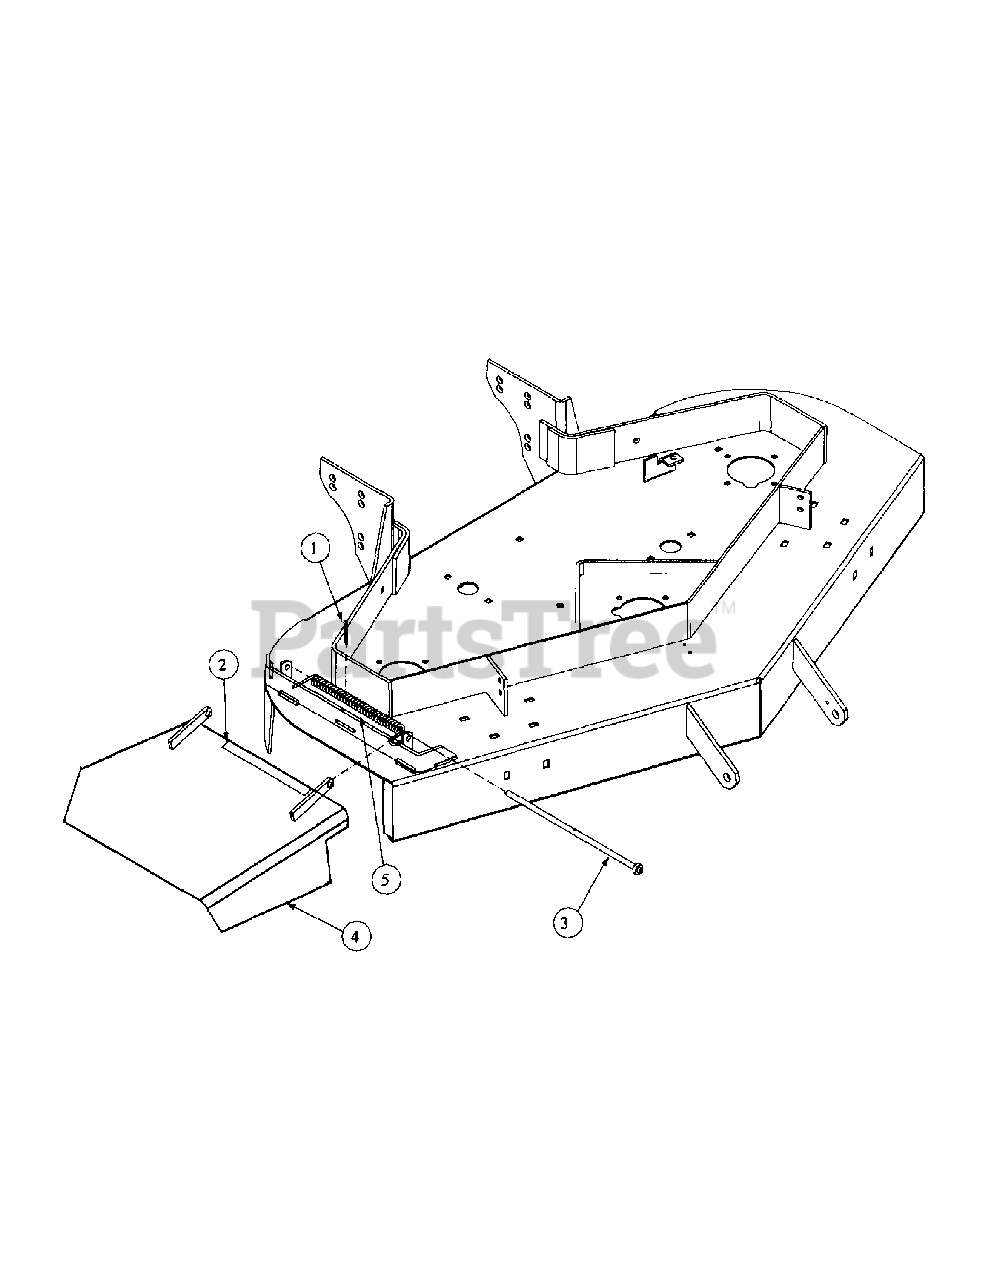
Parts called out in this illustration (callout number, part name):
1	Cotter Pin, 5/32 x 1-1/2, Zinc
2	Decal, Cut Line
3	Pin Deflector, Weldment
4	Chute 52, Weldment
5	Torsion Spring
